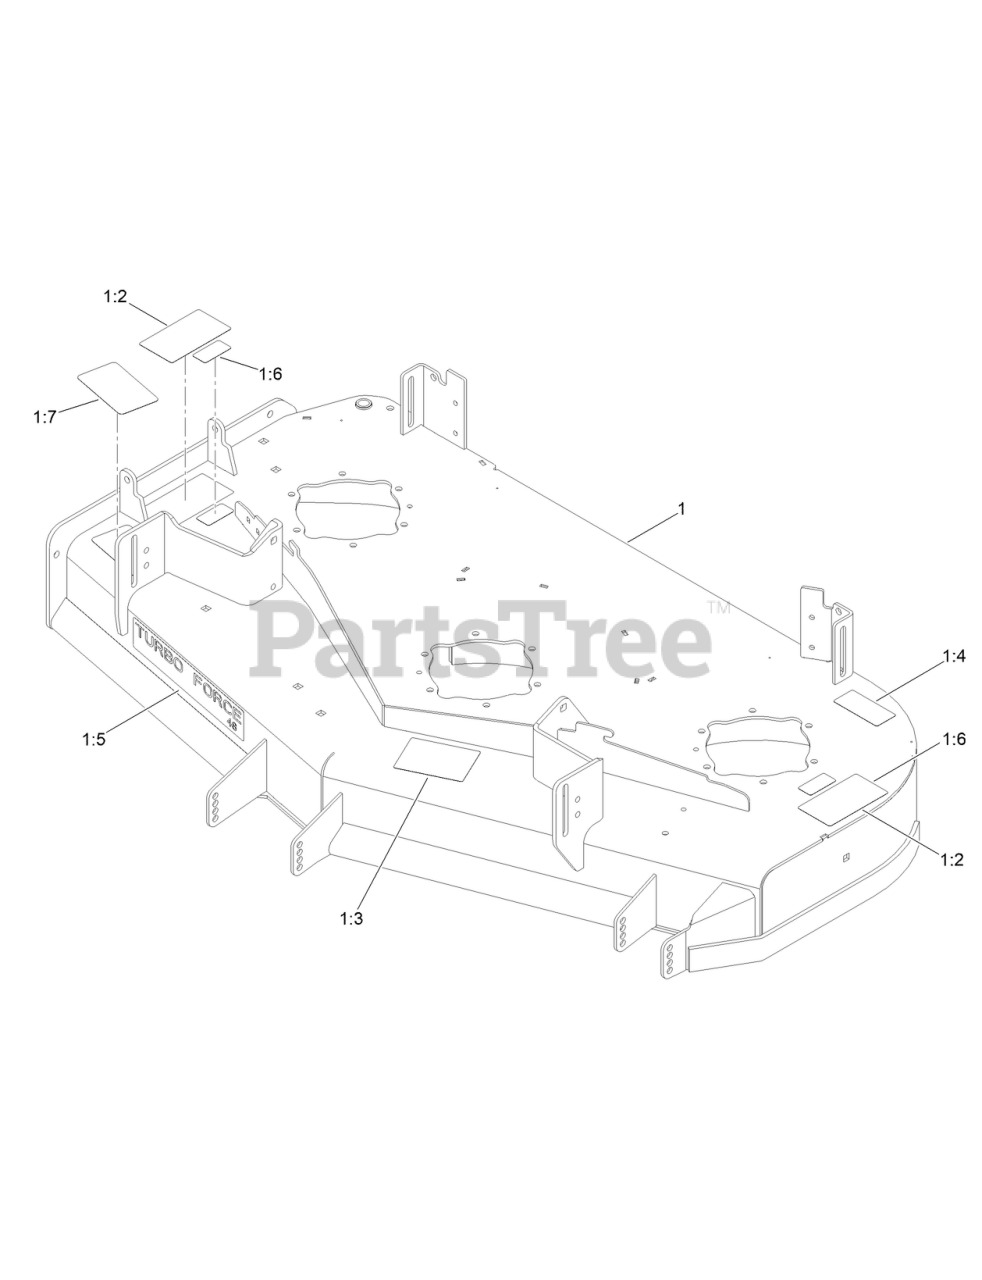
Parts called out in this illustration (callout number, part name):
1:2	DECAL-DANGER
1:3	DECAL-SCALP, ANTI
1:4	DECAL-DANGER
1:6	DECAL-NO SPRAY
1:7	DECAL-ADJUSTABLE BAFFLE
